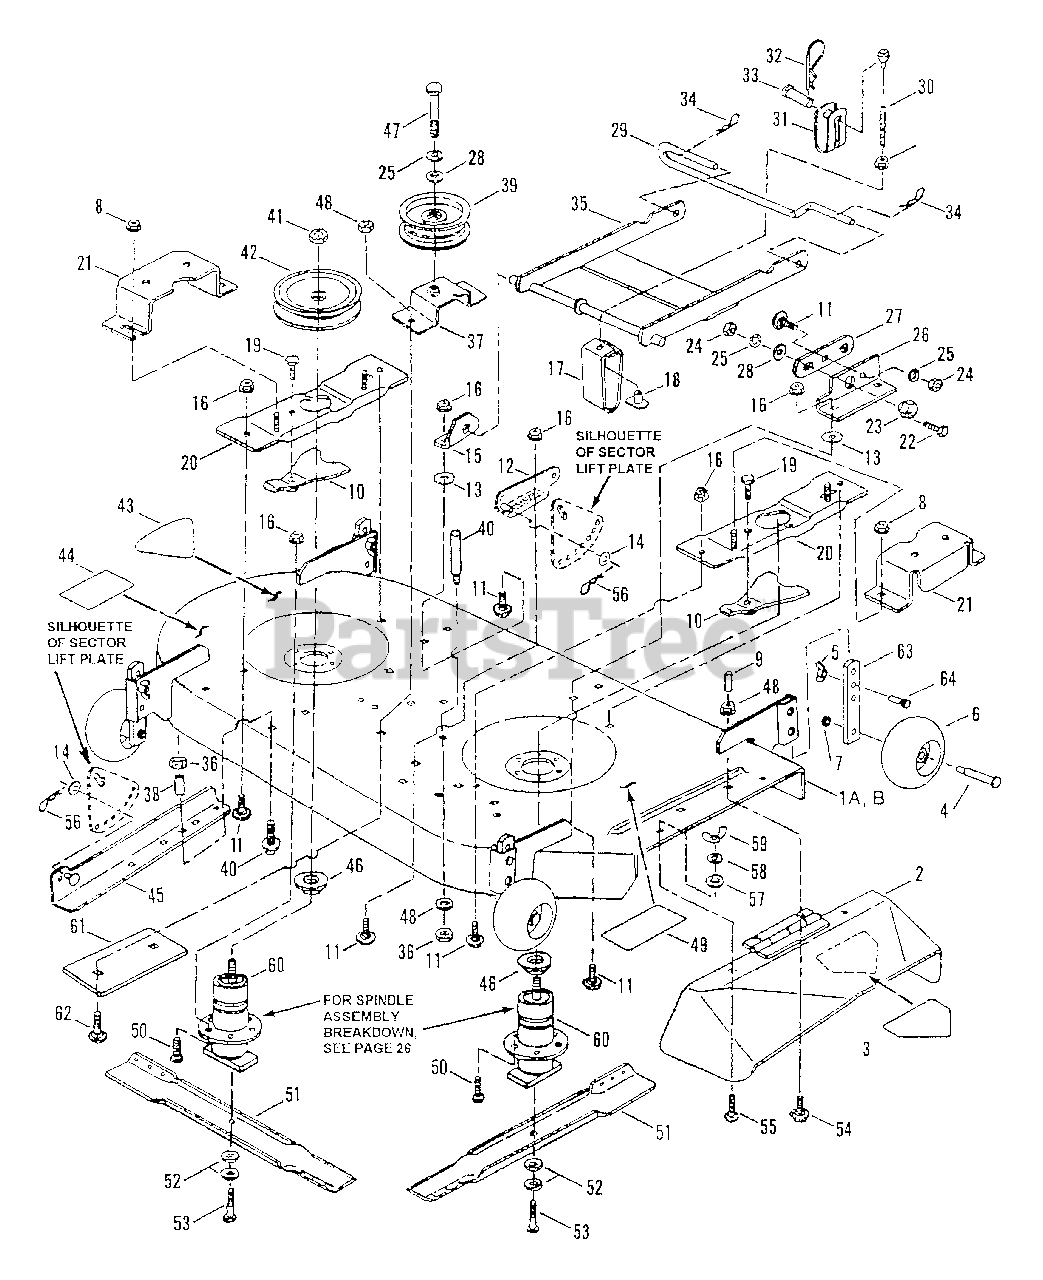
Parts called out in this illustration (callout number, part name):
1A	ASSEMBLY, 42" Cutting Deck
1B	ASSEMBLY, 42" Cutting Deck
2	DEFLECTOR, Side Discharge
3	DECAL - DANGER
4	BOLT, Gage Wheel
5	NUT, 3/8-16 Wing
6	WHEEL, Gage
7	NUT, 3/8-16 Hex Center Lock, Grade 5 or B
8	NUT, 5/16-18 Hex Flange Lock, Grade 5
9	CAP, Vinyl
10	ASSEMBLY, Spindle Lock
11	BOLT, 3/8-16 x 3/4" Carriage, Grade 2
12	BRACKET, Lift (Right Side)
13	WASHER, 3/8" Flat
14	WASHER, 3/8" Flat
15	BRACKET, Front Hanger (Left Side)
16	NUT, 3/8-16 Hex Flange Lock
17	BRACKET, Front Lift Arm Hanger
18	T-NUT, 5/16-18 Thread
19	BOLT, 3/8-16 x 1" Hex Flange Lock
20	ASSEMBLY, Spindle Brace
21	GUARD, Pulley
22	SCREW, 3/8-16 x 1" Hex Head Cap, Grade 5
23	ECCENTRIC, Leveling
24	NUT, 3/8-16 Hex
25	WASHER, 3/8 Split Lock
26	BRACKET, Front (Right Side)
27	LINK, Adjustment
28	WASHER, 3/8" Flat
29	PIN, Deck Hanger
30	CABLE, Deck Lift
31	CLEVIS, Lift Cable
32	PIN, Hair, 3/32 x 1-1/2"
33	PIN, Clevis, 3/8 x 1-1/16"
34	PIN, Hair, .148 x 2.62"
35	ASSEMBLY, Front Hanger
36	NUT, 3/8-16 Hex Center Lock, Grade 5 or B
37	BRACKET, Idler
38	SLEEVE, 1/2 x 13/32 x 3/8"
39	PULLEY, Idler 4-1/8"
40	BOLT, 3/8-16 x 1-1/2" Hex Flange Lock, Grade 5
41	NUT, 3/4-16 Hex Jam
42	PULLEY, Spindle
43	DECAL, 42" Deck
44	DECAL - CAUTION (Rotating Blades)
45	BRACKET, Deck Lift (Left Side)
46	WASHER, Spindle
47	BOLT, 3/8-16 x 1-3/4" Hex Flange Lock
48	NUT, 5/16-18 Hex Flange Lock, Grade 5
49	DECAL - CAUTION (Deflector in Place)
50	BOLT, 3/8-16 x 3/4" Hex Flange Lock
51	BLADE, 21" Cutter
52	WASHER, Cone, 13/32 x 1-13/32" Diameter
53	SCREW, 3/8-24 x 1-1/4" Hex Head Cap, Grade 5
54	BOLT, 5/16-18 x1" Short Neck Carriage, Grade 5
55	BOLT, 5/16-18 x 5/8" Carriage, Grade 5
56	PIN, Hair, 3/32 x 1-1/2"
57	RETAINER, 5/16" Bolt
58	WASHER, 5/16 Split Lock
59	WING-NUT, 5/16-18
60	ASSEMBLY, Spindle
61	PLATE, Support
62	SCREW, 5/16-18 x 1" Hex Head Cap, Grade 5
63	POST, Anti Scalp
64	SCREW, 3/8-16 x 1-1/4" Hex Head Cap Grade 5
